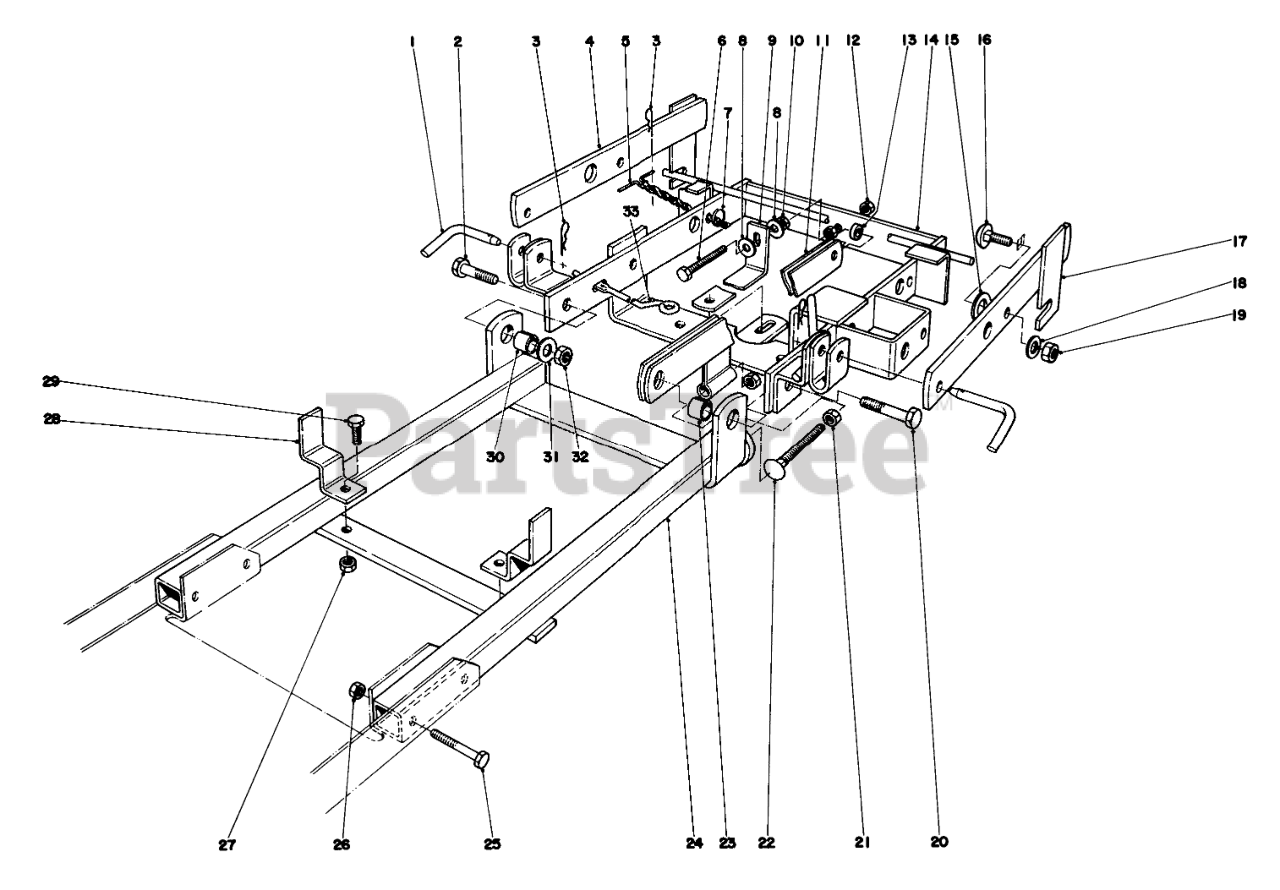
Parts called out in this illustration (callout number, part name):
1	Pin-Roller, Locating
2	SCREW-HH
3	TINNERMAN NUT
4	MountingBracket-R.H.
5	Chain & Toggle
6	SCREW-HH
7	Spring Clip
8	WASHER-FLAT
9	Bracket-Belt Adjust
10	NUT-JAM
11	Lift Extension
12	NUT-HEX
13	Spacer
14	Mounting Frame-Upper
15	Washer-Flat
16	Carriage Bolt
17	Mounting Bracket-L.H.
18	WASHER-LOCK
19	NUT-HEX
20	SCREW-HH
21	NUT-JAM
22	Carriage Bolt
23	Spacer-Bearing
24	Mounting Frame
25	SCREW-HH
26	NUT-LOCK, CONE
27	NUT-LOCK, CONE
28	Stop-Position
29	SCREW-HH
30	Spacer-Idler Pulley
31	WASHER-FLAT
32	1/2-13 CONELOCK NUT
33	Wire-Belt Guide
